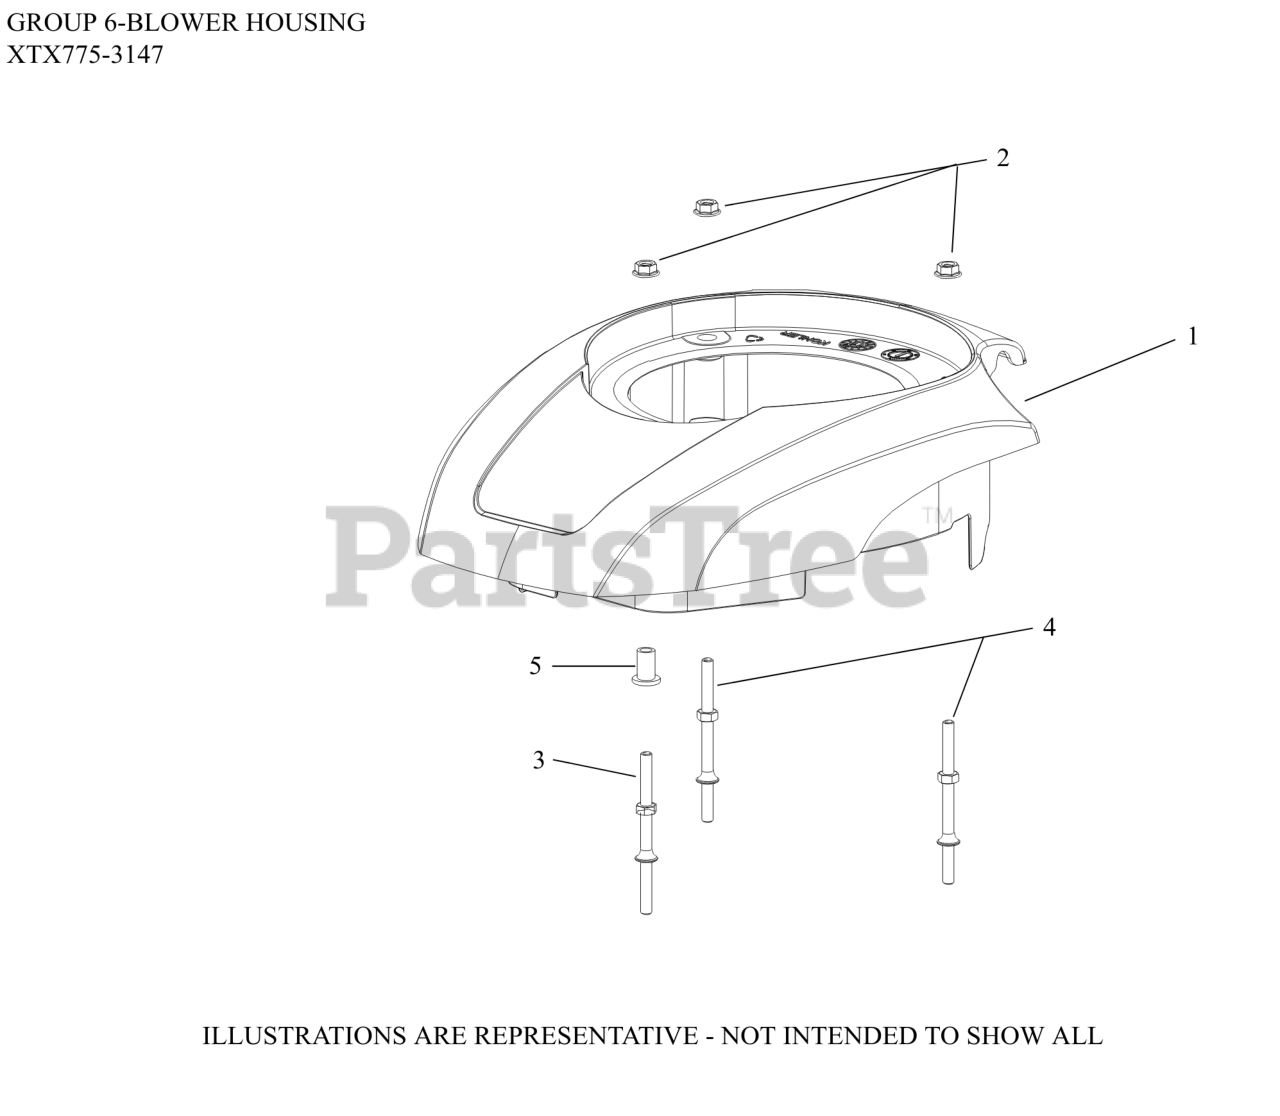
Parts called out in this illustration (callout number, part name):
1	COVER, ENGINE
2	NUT, HEX FLANGE (M6) - USE 14 100 16-S
3	STUD-USE 14 072 25-S
4	STUD-USE 14 072 26-S
